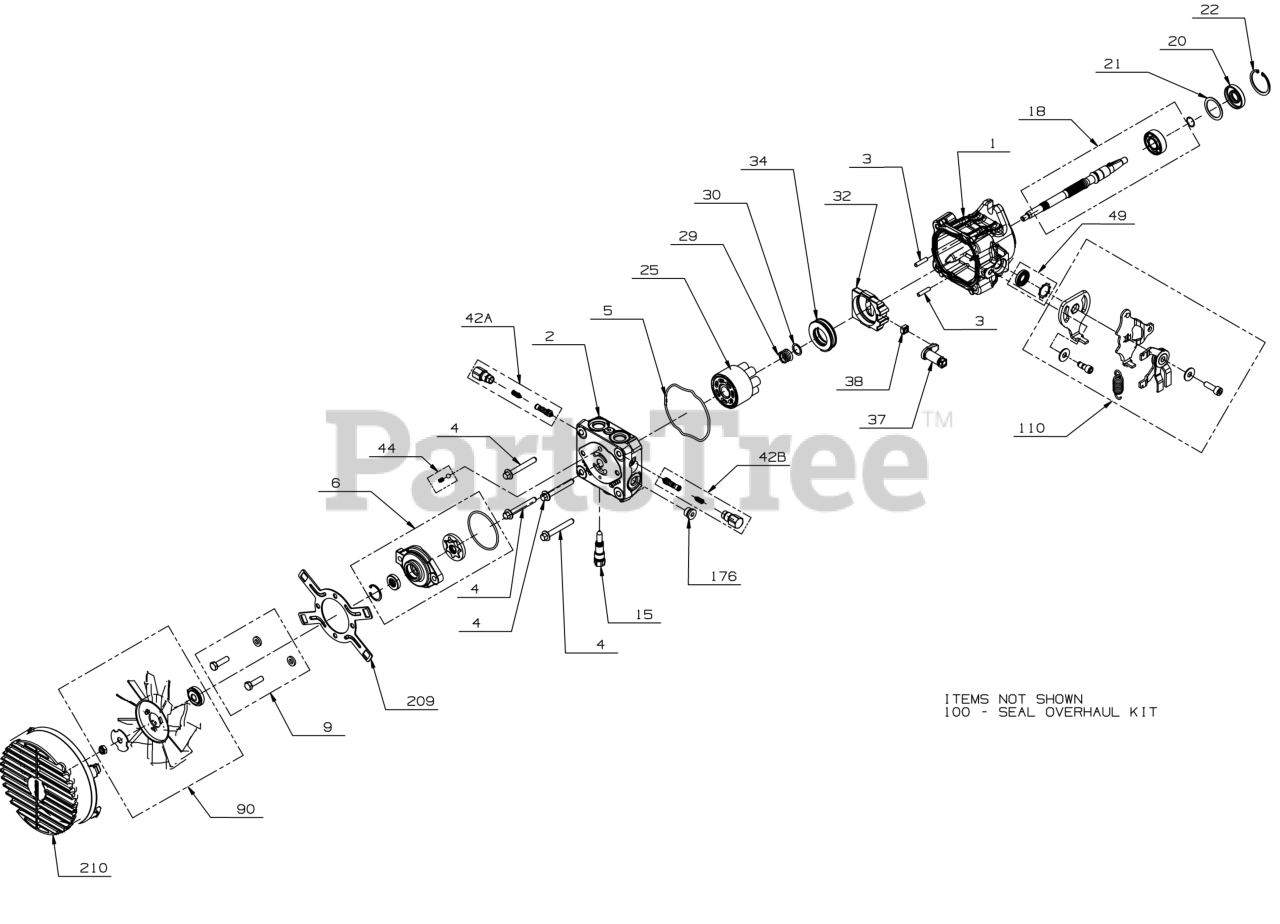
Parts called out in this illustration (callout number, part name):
1	KIT, HOUSING
2	END CAP
4	SCREW-FLANGE HEAD
5	O-RING PMP HOUSING
6	PUMP ASSEMBLY-CHARGE
9	BOLT KIT-CHARGE PU
15	VALVE KIT-BYPASS
18	SHAFT KIT-PUMP
20	LIP SEAL
21	WASHER 1.23X1.56X
22	RETAINING RING
25	BLOCK KIT-CYLINDER
29	SPRING-BLOCK
30	THRUST WASHER
32	SWASHPLATE, 10cc COATED & SANDED
34	THRUST BEARING
37	ARM-TRUNNION
38	GUIDE-SLOT
42A	KIT-SHOCK VALVE
42B	KIT-SHOCK VALVE
44	RELIEF KIT-CHARGE
49	SEAL KIT-TRUNNION
90	FAN KIT-6" 10 BLAD
100	SEAL KIT-OVERHAUL
110	SCISSOR KIT-R T N
176	PLUG-STRAIGHT THRE
209	BRACKET-SHROUD
210	SHROUD, 6 INCH
